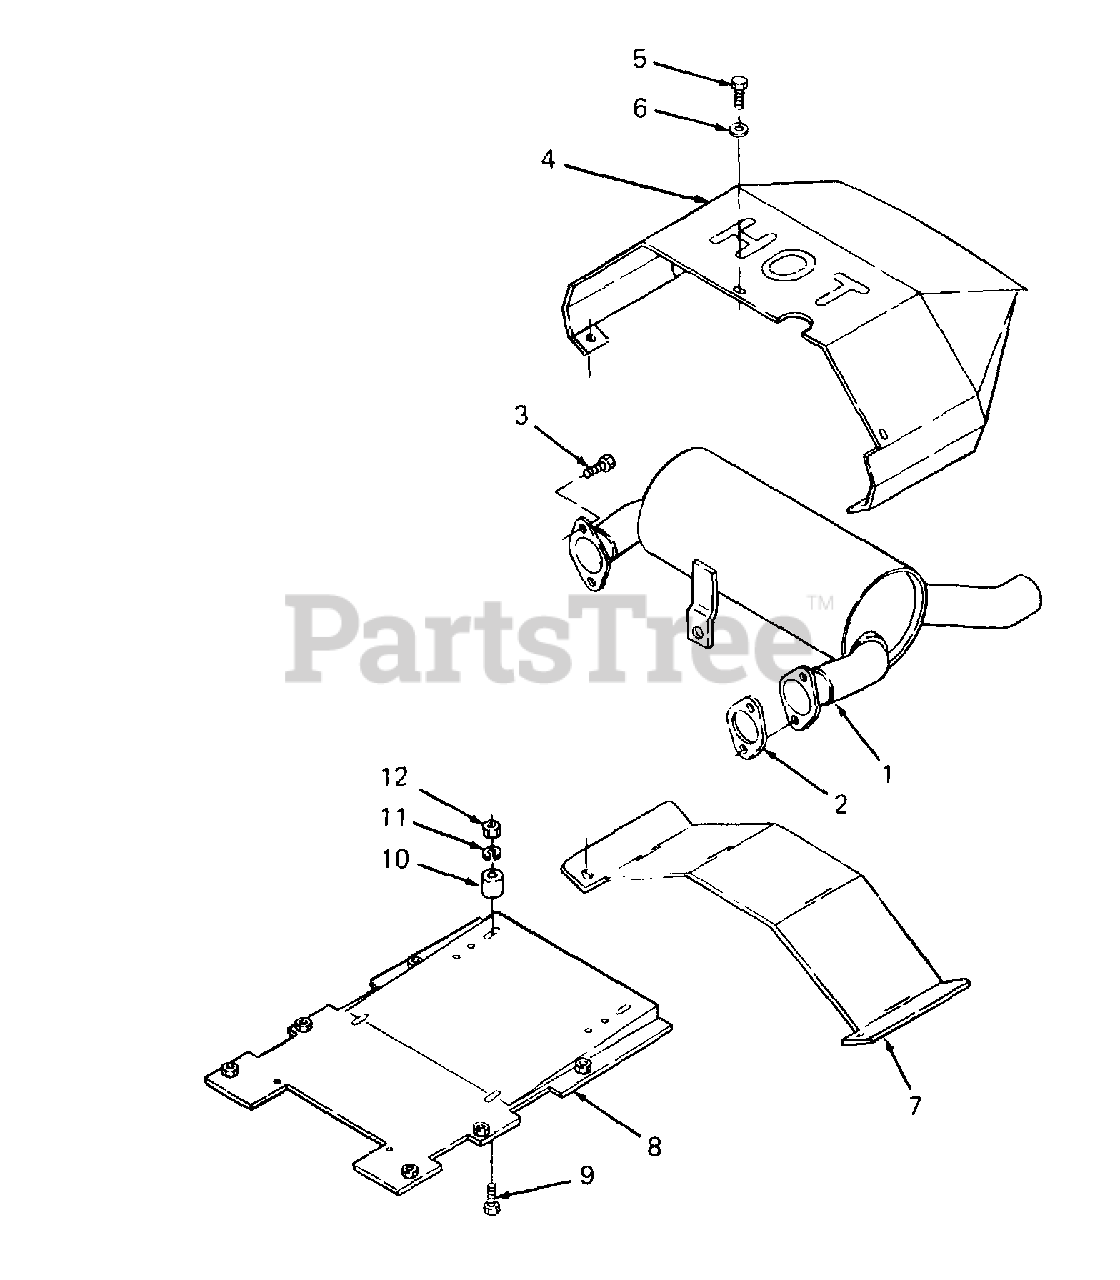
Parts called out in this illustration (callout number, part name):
2	Gasket, Exhaust
3	Screw, Sems
4	Ducting, Muffler
5	Bolt, Hex, M6-1.0 X 10 mm Lg GR5
6	Washer, Flat, .281 X .50 X .063 Thk
7	Shield, Muffler Heat
9	Screw, Hex Cap, 5/16-18 X 3.25 Lg GR5
11	Washer, Lock, 5/16
12	Nut, Hex, 5/16-18
